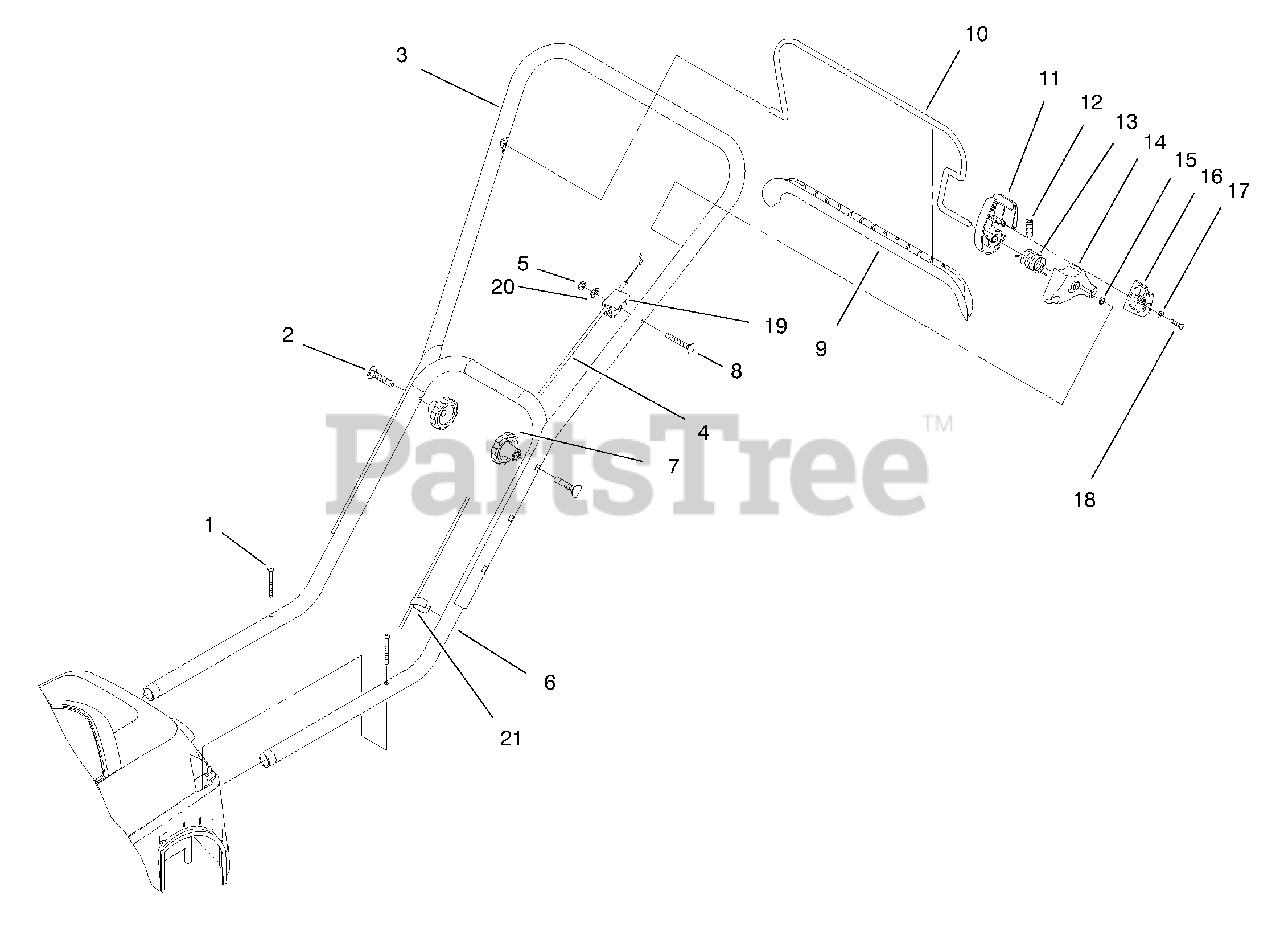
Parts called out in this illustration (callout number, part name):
1	Screw-PPH
2	Screw-Handle
3	Handle-Upper
4	Cable-Control
5	Nut-Lock
6	Handle-Lower
8	Screw-Handle
9	Cover-Bail
11	Housing-Bail
12	Spring-Slide
13	Spring-Bail
15	Nut-Push
17	Washer-Flat
19	Support-Cable
20	Washer-Flat
21	Clip-Cable
